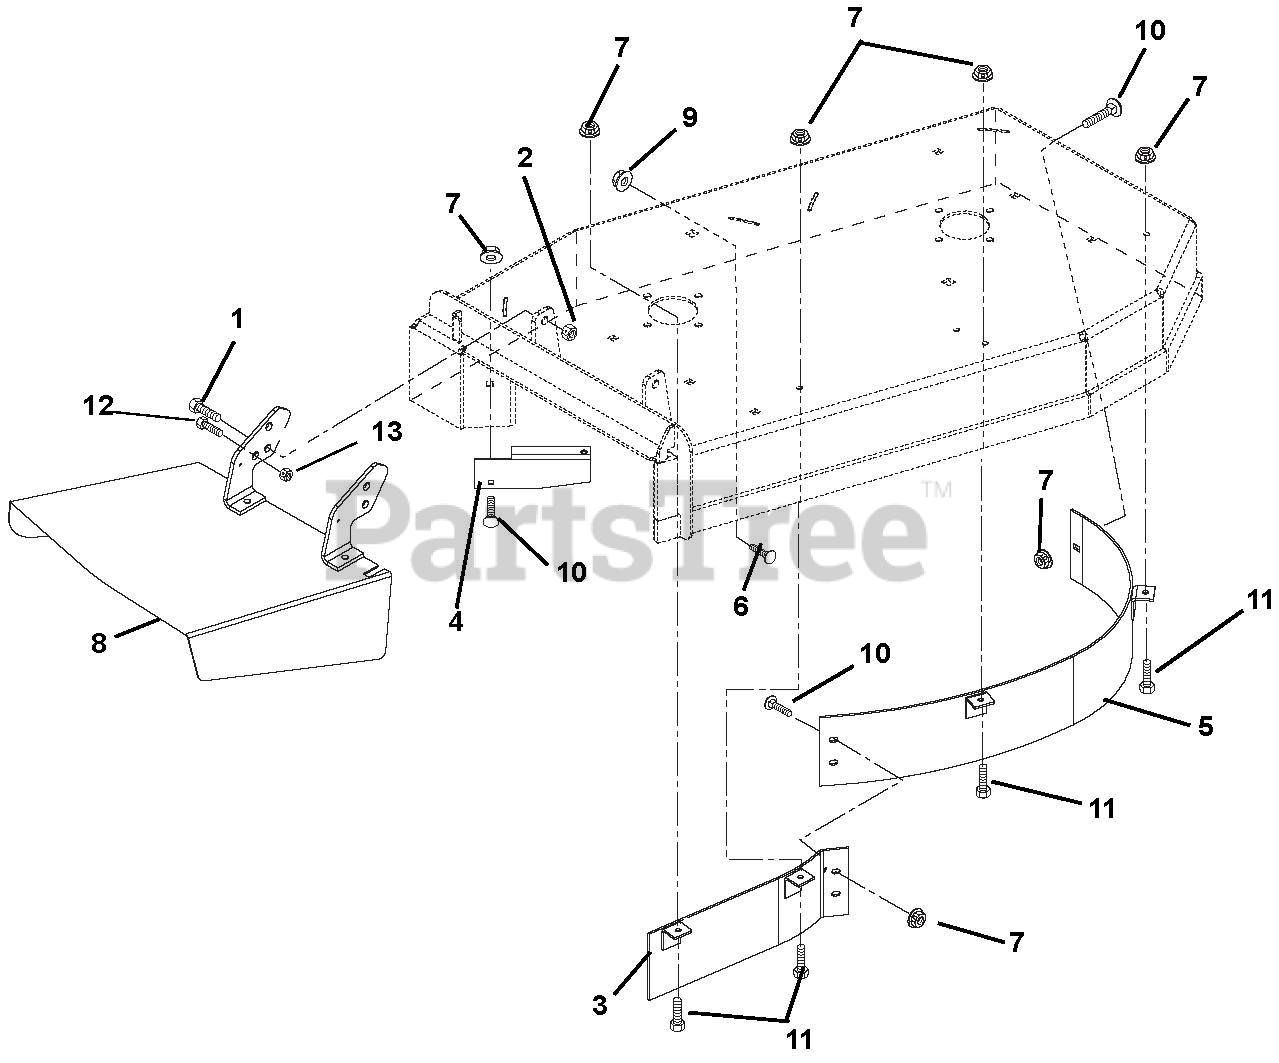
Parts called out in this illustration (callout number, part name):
1	Bolt, Hex .50-13 x 1.25 Grade 5
2	Nut, Locking-Nylon .50-13
3	Weldment- Upper Baffle Right
4	Deflector 32"
5	Weldment, Upper Baffle Left
6	Bolt, Round Head Square Neck .38-16 x 1.00 Grade 5
7	Nut, Locking-Top-Flange .31-18
8	Chute, Discharge
9	Nut, Locking-Top-Flange .38-16
10	Bolt, Round Head Square Neck .31-18 x .75 Grade 5
11	Bolt, Hex .31-18 x .75 Grade 5
12	Bolt-Hex .25-20 x .75 Grade 5
13	Nut-Locking-Nylon .25-20
